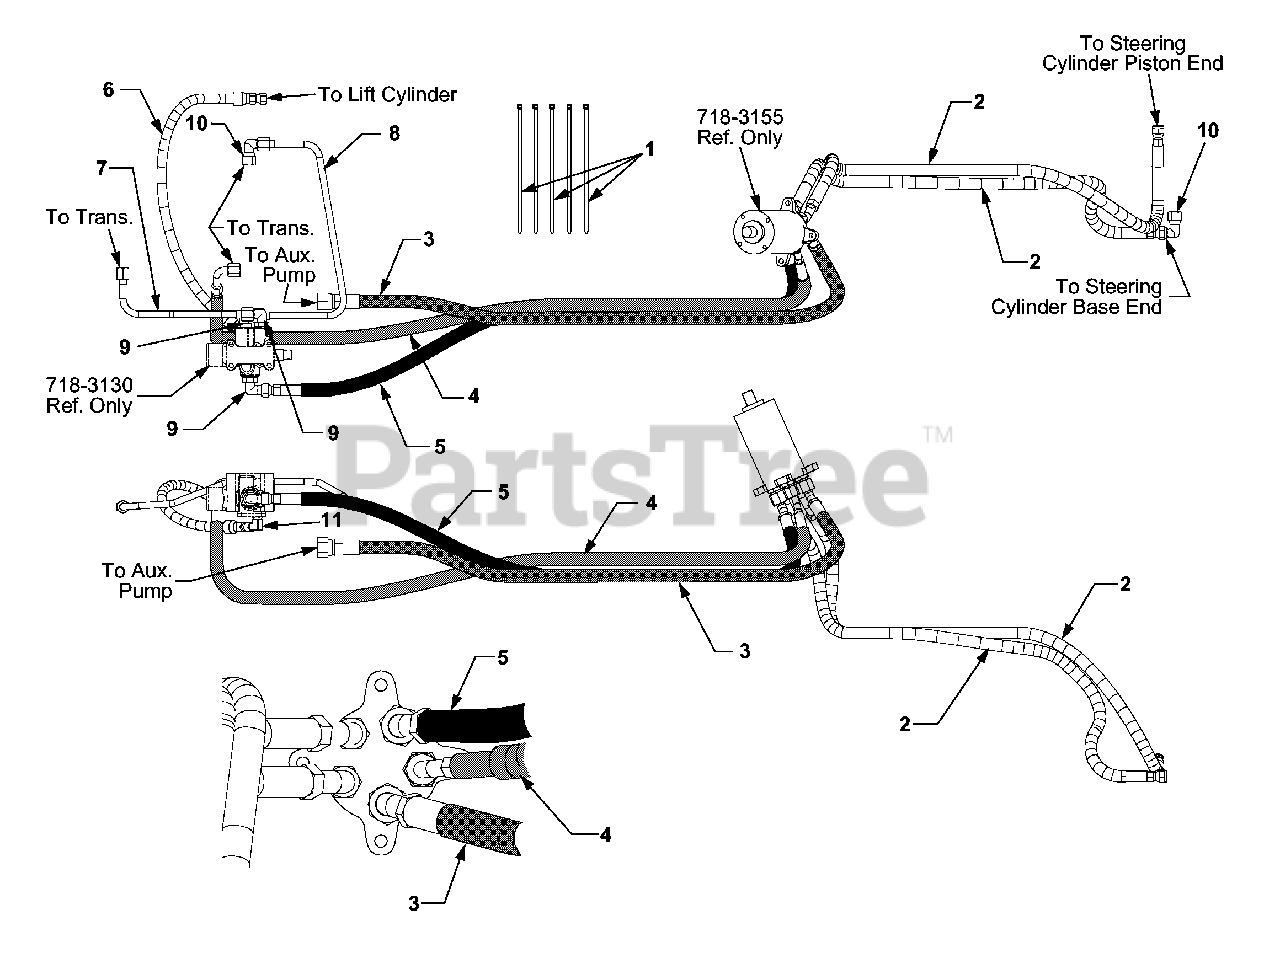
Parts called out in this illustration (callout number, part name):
1	Tie, Cable
2	Hose, Steering
3	Hose, Steering Pressure
4	Hose, Steering - Tank
5	Hose, Lift Inlet
6	Hose, Lift Cylinder
7	Tube, Cylinder Return
8	Tube, Lift Return Line
9	Fitting, 90 Degree
10	Fitting, 90 Degree Swivel
11	Fitting, 90 Degree
718-3130	VALVE-HYDRAULIC LI
